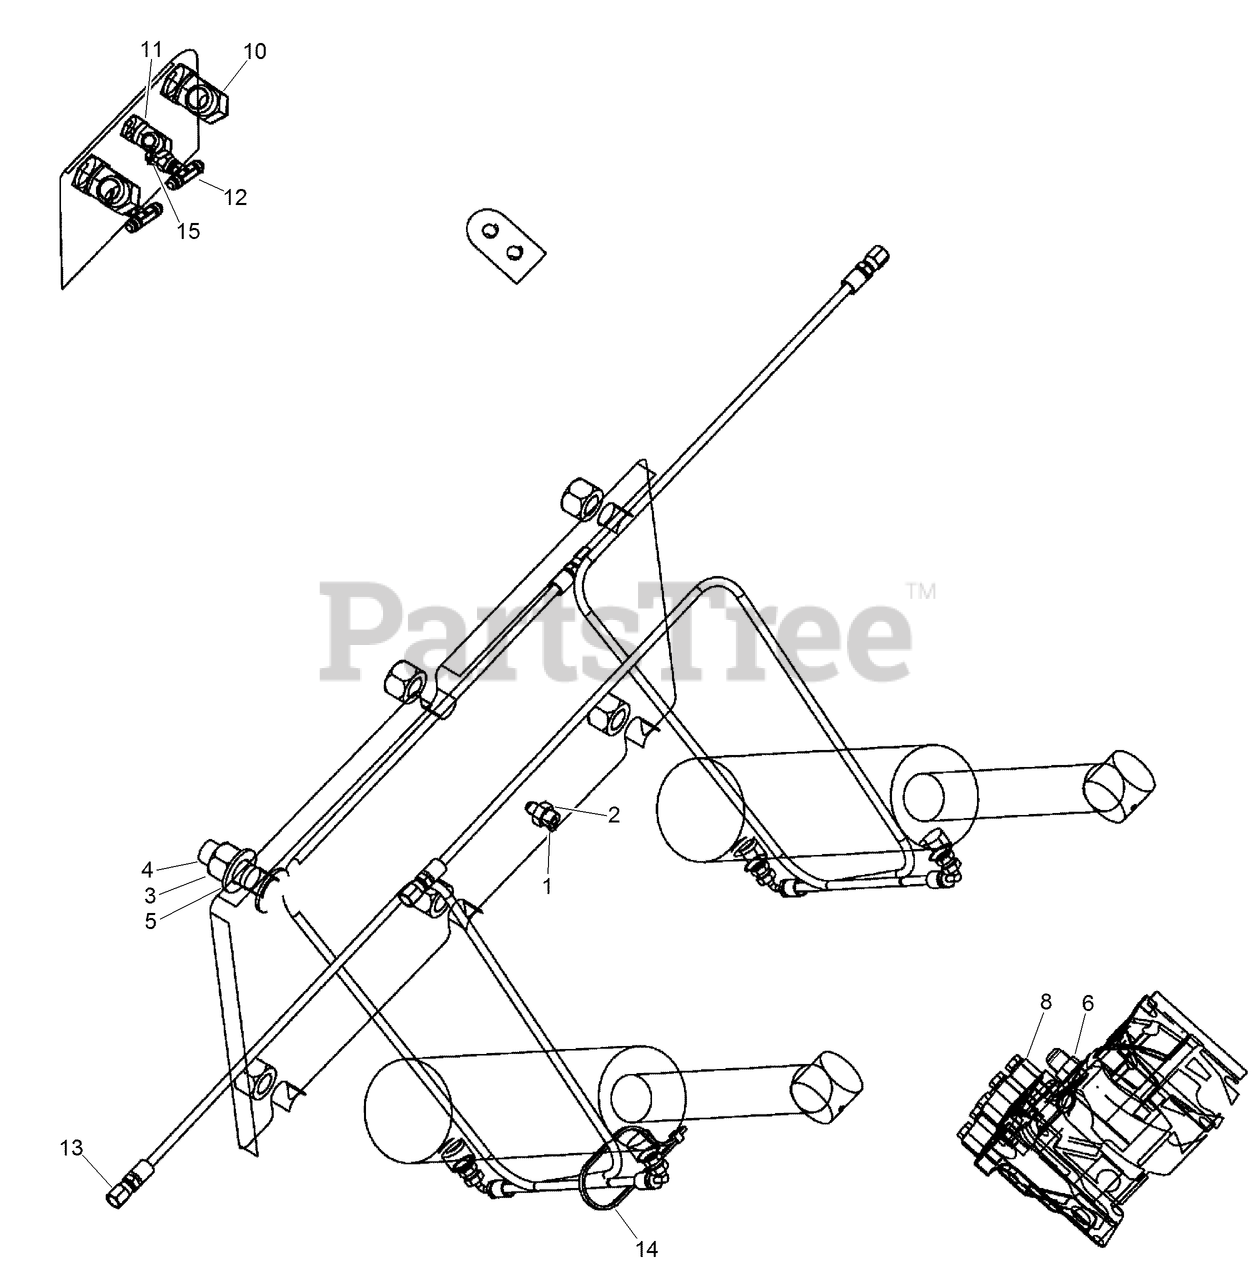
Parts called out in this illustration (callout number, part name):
1	ASM-Hose, Tilt
2	CONNECTOR
4	SCREW-CAP, HH
6	CONNECTOR-Str Thd 5/8, 37FL-ORB 5/8
8	HYD FLANGE KIT
10	FITTING-ELBOW, 90
11	ELBOW-90 Swivel 37FL 5/8 Tube
12	ADAPTER - Tee, FJIC / MJIC
13	HOSE ASSEMBLY - Hydraulic
14	STRAP-TIE
15	ORIFICE - 0.047 Inline
